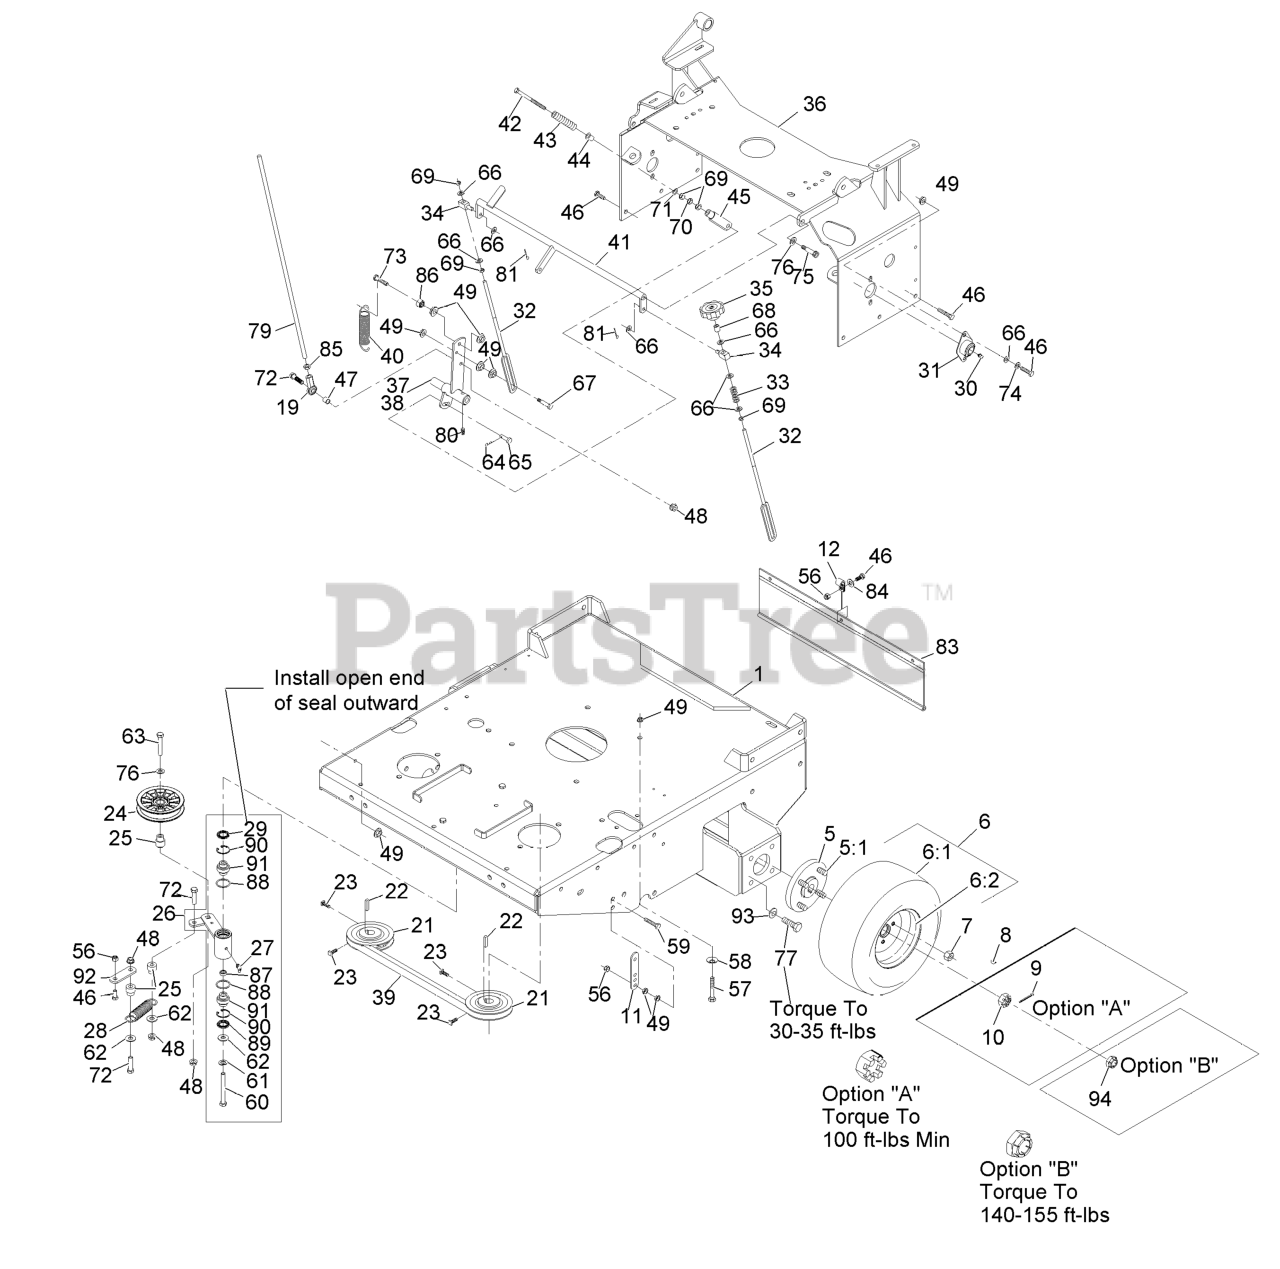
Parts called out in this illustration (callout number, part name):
5:1	STUD-WHEEL
6	ASM, DRIVE TIRE
7	NUT-LUG
8	KEY-WOODRUFF
9	PIN-COTTER
10	NUT-HEX, SLOTTED
11	TAB-SPRING, EXTENSION
12	CLIP-LOOM
19	JOINT-BALL END, LH
21	SHEAVE ASM
23	SCREW-SET
24	PULLEY-IDLER, FLAT
25	BUSHING-IDLER
26	KIT,IDLER ARM W/BRGS.
27	FITTING-GREASE, 90 DEG
28	SPRING-EXTENSION
29	SEAL-LIP, SINGLE
30	FITTING-GREASE
31	BEARING-FLANGE, SIDE
32	LINK,SPEED CONTROL
33	SPRING-COMPRESSION
35	KNOB-TRACKING
36	WLD,FUEL TANK SUPPORT TT
37	WLD,LH CONTROL ARM
39	BELT,COG A-59.5
40	SPRING-EXTENSION
41	WLD,CRANK SPEED CNTRL
42	BOLT-RETURN, NEUTRAL
43	SPRING,COMPRESSION (NEUT)
44	BUSHING-FLANGED
45	YOKE-ADJUSTABLE
46	SCREW-HH
47	TUBE,PUMP LINK SPACER
48	NUT-HHF, WHIZ
56	NUT-LOCK, NI
57	SCREW-HH
58	WASHER-BELLEVILLE
59	BOLT-TAP, HH
60	SCREW-HH
61	WASHER-LOCK
62	WASHER-FLAT
63	SCREW-HH
64	PIN-COTTER
65	PIN-CLEVIS
66	WASHER-PLAIN
67	SCREW-HH
69	NUT-HEX
70	NUT-JAM
71	WASHER-FLAT
72	SCREW-HH
73	SCREW-HH, SPECIAL
74	WASHER-LOCK
75	SCREW-HSH
76	WASHER-FLAT
77	SCREW-HH
79	LINK,DRIVE (PLTD)
80	SCREW-SET
81	PIN-COTTER
83	SHIELD,DRAG
84	WASHER-FLAT
85	NUT-HEX JAM, LH
86	NUT-JAM
89	SEAL-LIP, DOUBLE
90	RING-SNAP
91	BEARING-SPHERICAL
92	ARM-LIFT, DECK
93	WASHER-BELLEVILLE
94	NUT-LOCK
